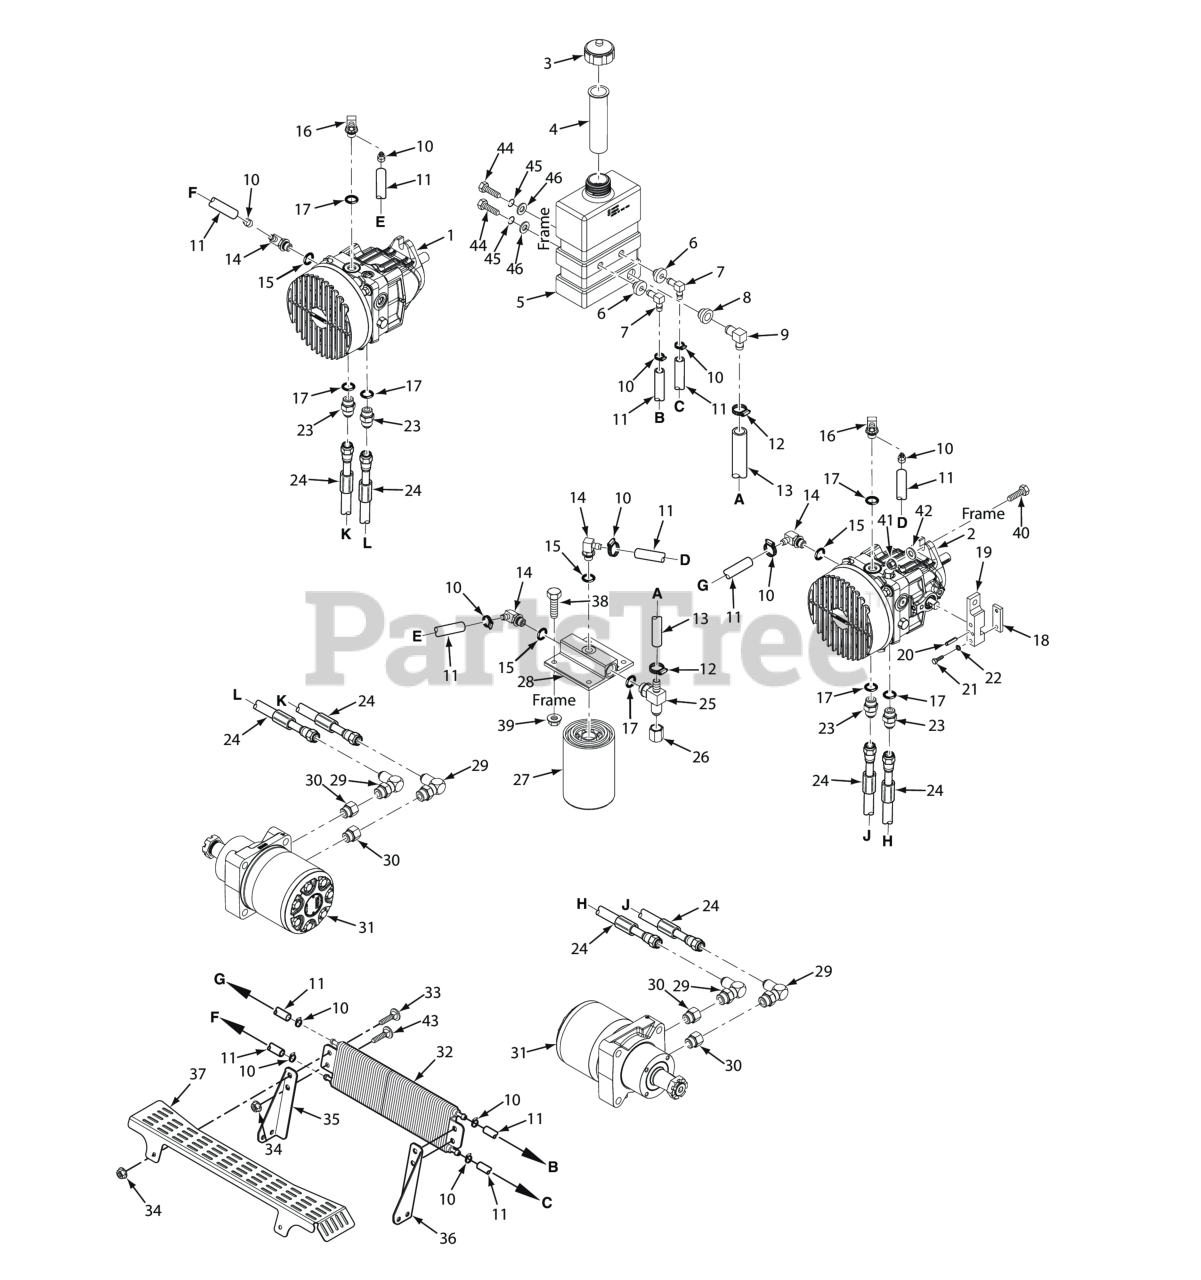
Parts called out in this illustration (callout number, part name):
1	Pump w/Fan, Right Hand (791DFI,35BVAC)
2	Pump w/Fan, Left Hand (791DFI, 35BVAC)
3	CAP, HYDRAULIC TANK
4	Insert, Filler Neck
5	Hydraulic Tank Assy., STTII
6	Bushing, 0.56" Dia. Viton
7	Elbow, 90 Degree, 9/16-18 JIC x 9/16 O-Ring
8	Bushing, 0.78" Dia. Viton
9	Fitting, 90 Degree - 1/2" Hose
10	Clamp, .69" Max. / .25" Min. Dia.
11	Hose, 3/8" ID - 10-1/4" Long (Order By The Inch)
12	Clamp, Cable 3/4" I.D.
13	Hose Assembly, 1/2" ID (Oil Reservoir to Filter Base)
14	Elbow, 90 Degree - 9/16" O-Ring x 3/8" Hose
15	"O" RING, 5/64 X 15/32 ID
16	Elbow, 90 Degree - 3/4" O-Ring x 3/8" Hose
17	"O" RING, 3/32 X 5/8" ID
18	Clamp Plate, Pump Control
19	Block, RH Pump Control
20	Roll Pin, Spring 3/16 x 3/4"
21	Bolt, Hex Head, 1/4-20 x 1-1/2"
22	Lockwasher, 1/4� Spring
23	Fitting, Union 3/4-16 JIC X O-Ring
24	Hose Assembly
25	Tee, 3/8" O-Ring x JIC x 1/2" Hose
26	CAP, 3-4-16 JIC
27	FILTER, SPIN-ON LUBE
28	Filter Head Assembly
29	ELBOW, 90DEG, 7/8-14 JIC X 7/8-14 O-RING
30	Bushing, 7/8"-14 JIC x 3/4"-16 O-Ring
31	Wheel Motor, Parker TG - 18ci.
32	Cooler, Transmission
33	Serr. Fl. Hex Head CPSCR, 1/4-20 x 3/4"
34	NUT, 1/4-20 SERRATED FLANGE HEX HEAD
35	Mounting Bracket, Cooler - RH
36	Mounting Bracket, Cooler - LH
37	Screen Guard, Kohler EFI (LP)
38	Bolt, Heax Head 5/16-18 x 1" (48V / 52V)
39	Nut, Serrated Flange 5/16-18 (Right Front Engine Mounting, Briggs and Kohler Only)
40	Bolt, Hex Head, 3/8-16 x 1-1/2"
41	HEX NUT, ELASTIC STOP LOCK, 3/8-16
42	Flatwasher, 3/8 (.391 x .938 x .105 HD) Grade 8
43	Bolt, Carriage 1/4-20 x 1/2"
44	BOLT, SERRATED FLANGE HEX HEAD 5/16-18 X 3/4"
45	Lockwasher, 5/16 (.317 x .586 x .078) Helical Spring
46	Flatwasher, 5/16-.375 x .875 x .083 (35BV & 37BV-EFI)
